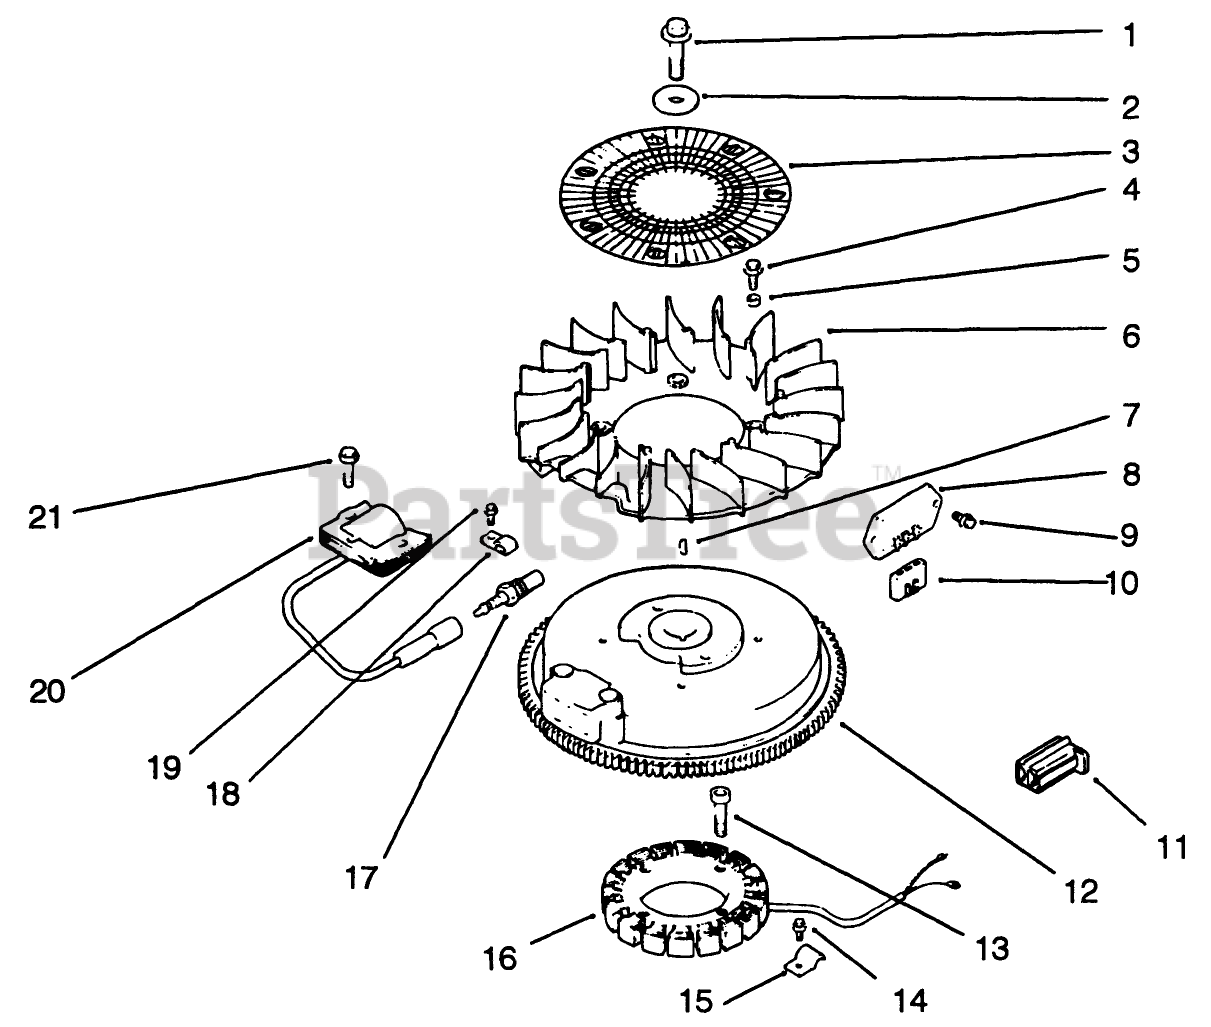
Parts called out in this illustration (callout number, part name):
3	Screen-Grass
4	Screw-Fan
5	Spacer-Fan
6	Fan (Only On: 72042, 72063, 72062, 72043)
8	Rectifier-Unregulator
10	Connector
11	Connector
12	Flywheel
15	Clip-Stator Harness (Only On: 72042, 72063, 72062, 72043)
16	Stator 15 amp.
17	Spark Plug
20	Module-Ignition (Only On: 72042,72043,72062,72063)
